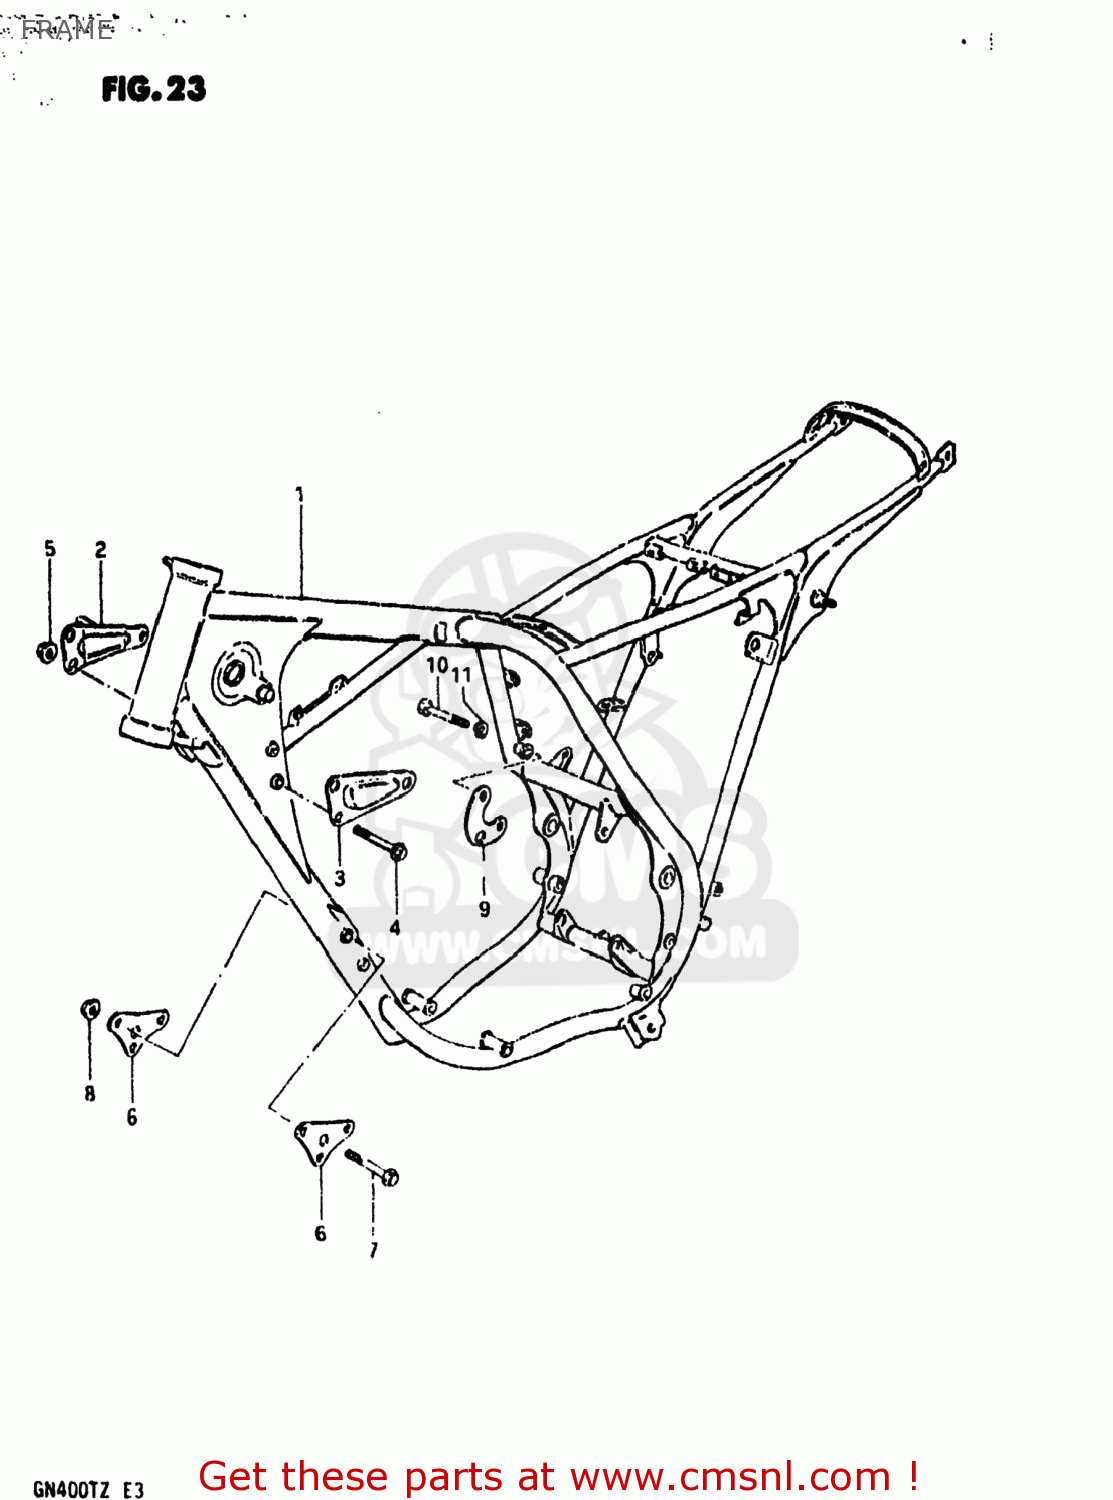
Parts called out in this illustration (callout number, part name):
1	FRAME
2	PLATE,ENGINE MOUNTING,UPPER
3	PLATE,ENGINE MOUNTING
4	BOLT (6X70)
5	NUT
6	PLATE,ENGINE MOUNTING
7	BOLT (8X70)
8	NUT
9	PLATE,ENGINE MOUNTING
10	BOLT 8X55
11	LOCK WASHER
